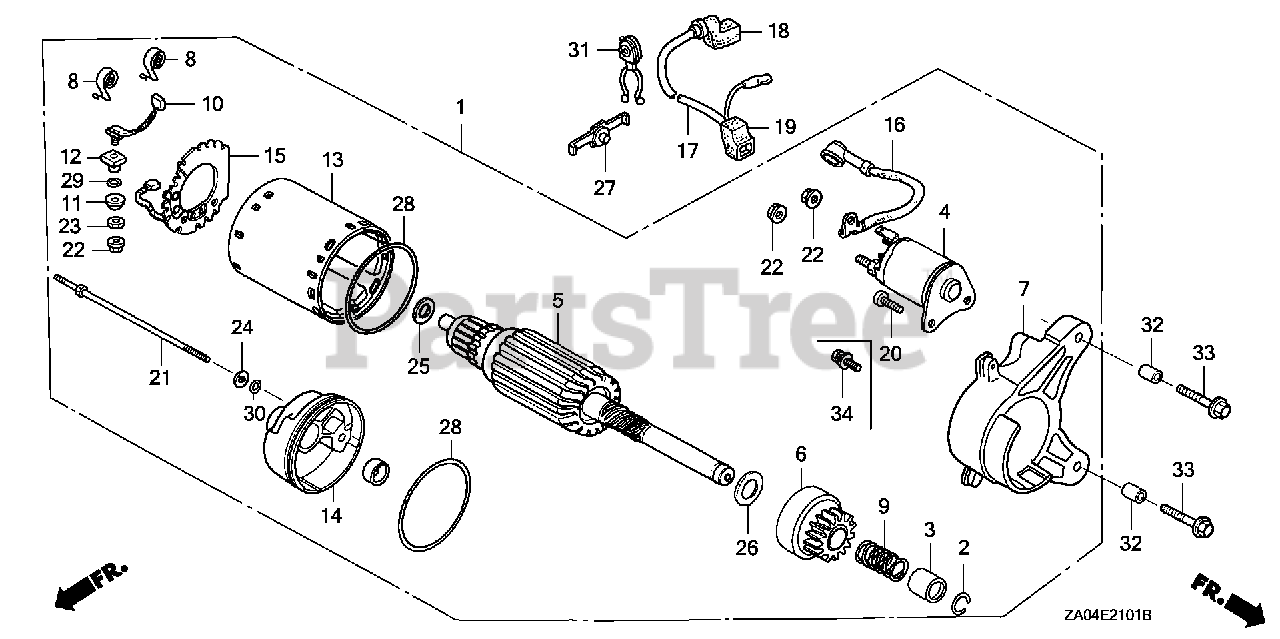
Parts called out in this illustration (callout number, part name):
1	STARTER MOTOR ASSY.
2	RING, SNAP
3	COLLAR, CLUTCH STOP
4	CONTACTOR ASSY.
6	CLUTCH ASSY., OVERRUNNING
7	HOUSING, DRIVE SIDE
8	SPRING, BRUSH
11	BUSH, INSULATION (NOT AVAILABLE)
12	BUSH, INSULATION (NOT AVAILABLE)
14	FRAME, STARTER END
15	PLATE, BRUSH HOLDER
16	WIRE, WATER COVER
16	WIRE, WATER COVER (NOT AVAILABLE)
20	BOLT
20	SCREW-WASHER (5X14)
21	BOLT, THROUGH (NOT AVAILABLE)
21	BOLT, THROUGH
24	WASHER, STEEL PLATE (NOT AVAILABLE)
32	PIN, DOWEL (10X16)
33	BOLT, FLANGE (8X40)
